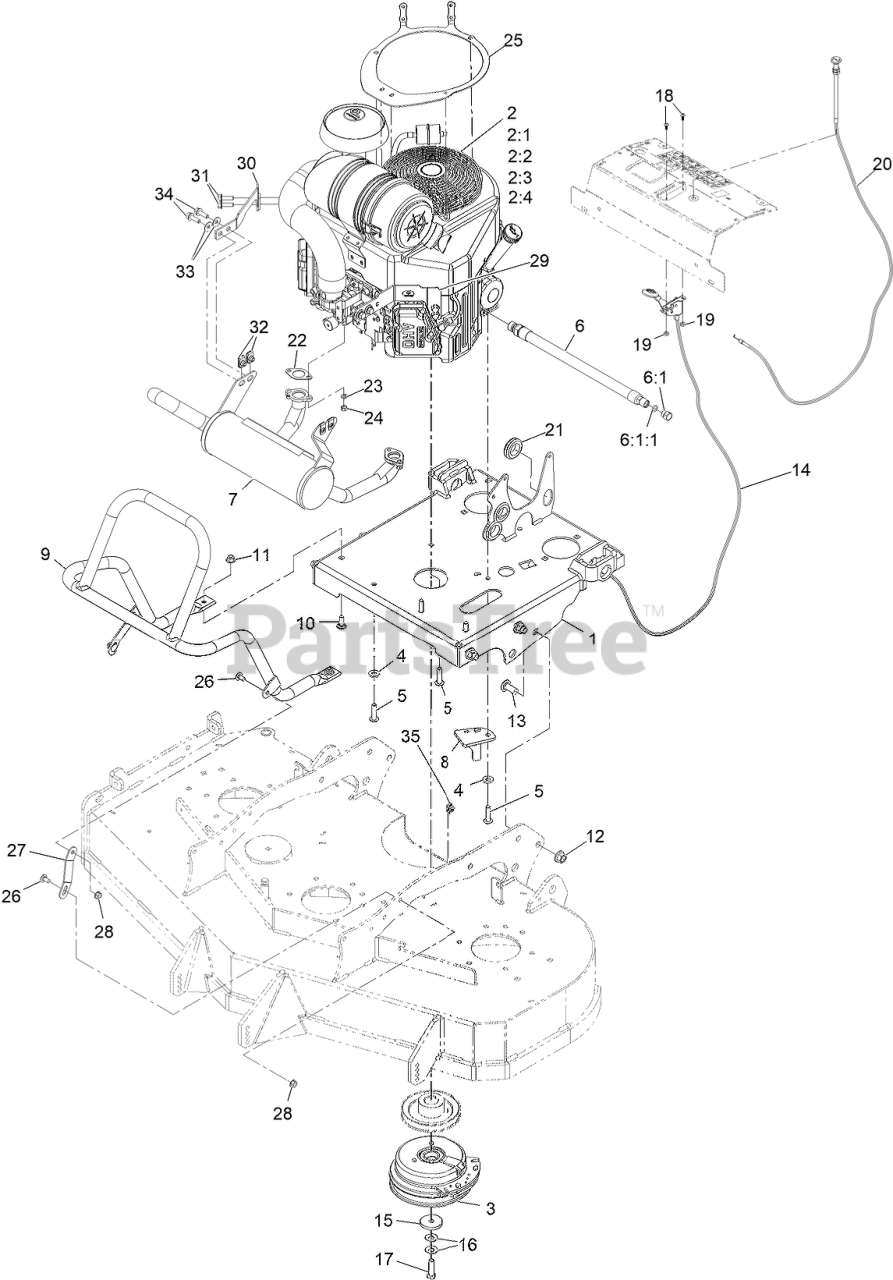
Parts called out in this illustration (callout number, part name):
1	WLD-ENGINE DECK
2:1	Kawasaki 49065-7007Engine Oil Filter
2:2	Kawasaki 49019-7005 Fuel Filter
2:3	Kawasaki 11013-7045 Safety Filter
2:4	Kawasaki 11013-7044 Engine Air Filter
4	WASHER-BELLEVILLE
5	SCREW-BHTF
6	ASM, ENGINE OIL DRAIN HOS
6:1	PLUG-HH
6:1:1	O-RING
7	MUFFLER-KAWASAKI
8	ASM-CLUTCH ANCHOR
9	Tube-Guard Muffler
10	SCREW-CARR
11	NUT-HF, NI
12	Nut-Lock 1/2-13
13	SCREW-CARR, SHORT NECK
14	CONTROL,THROTTLE
15	WASHER-CLUTCH
16	WASHER-SPRING
17	SCREW-HH 7/16-20 X 1 1/2 W/LOCTITE
18	BOLT-CARR
19	NUT-LOCK, NI
20	CABLE-CHOKE
21	GROMMET
22	GASKET-EXHAUST
23	WASHER-LOCK
25	BRACKET- ENGINE FILTER
26	SCREW-CARR
27	Strap, Muffler Guard
29	BRACKET-MUFFLER, FRONT
30	BRACKET-MUFFLER, REAR
31	SCREW-HHF
33	WASHER-BELLEVILLE
34	SCREW-HHF
35	Clip-Edge W/Tie, Perpendicular
